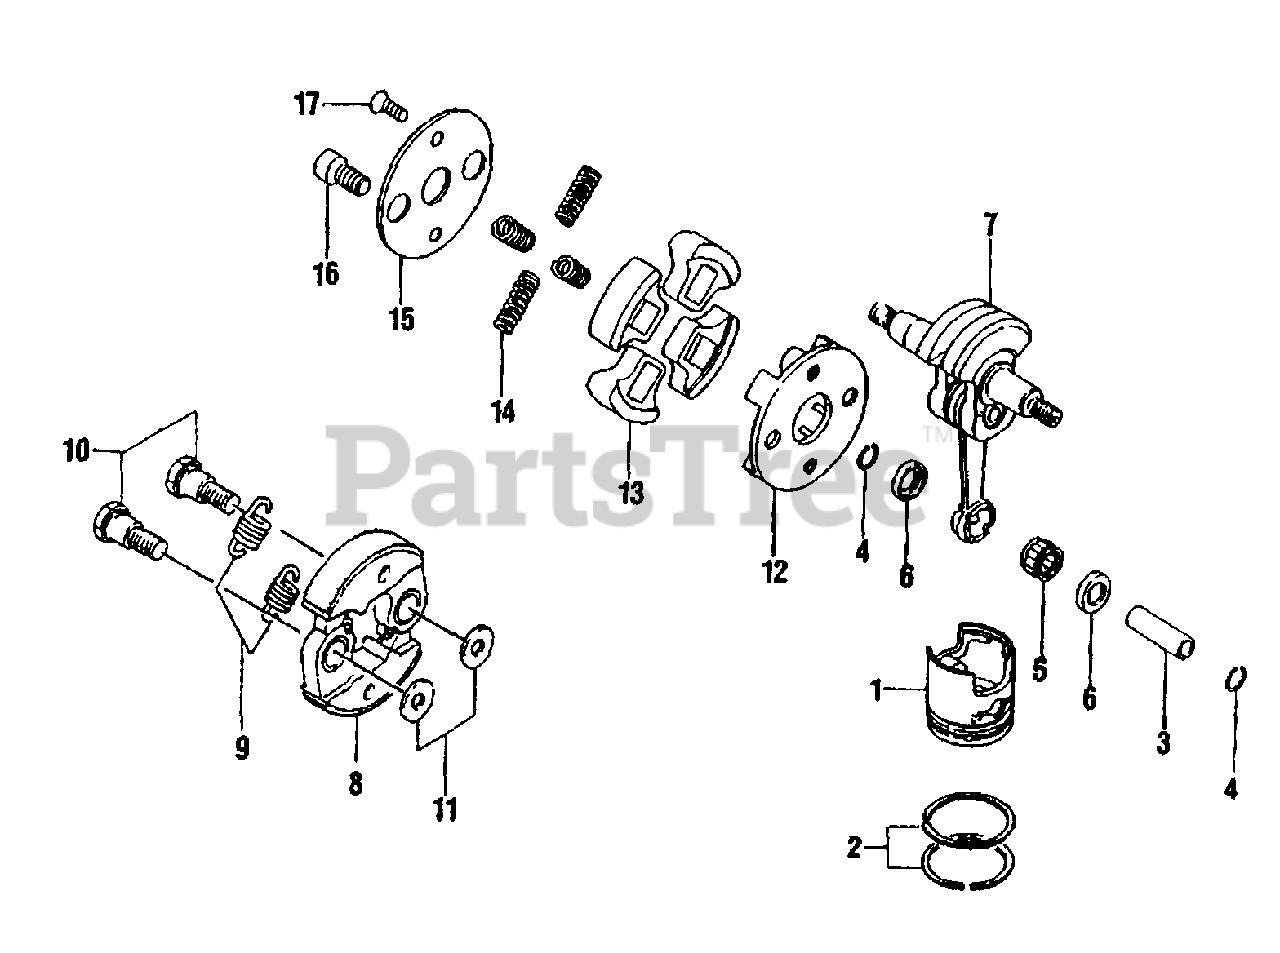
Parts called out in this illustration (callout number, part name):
2	RING, PISTON
2	GASKET, CYLINDER
3	PIN, PISTON
4	RING, RETAINING
5	BEARING, NEEDLE
6	WASHER, THRUST
7	CRANKSHAFT ASSY
8	SHOE, CLUTCH
9	SPRING, CLUTCH
10	BOLT, CLUTCH
11	WASHER
12	HUB, CLUTCH
13	SHOE, CLUTCH
14	SPRING, CLUTCH
15	PLATE, CLUTCH
16	BOLT, CLUTCH
17	SCREW
